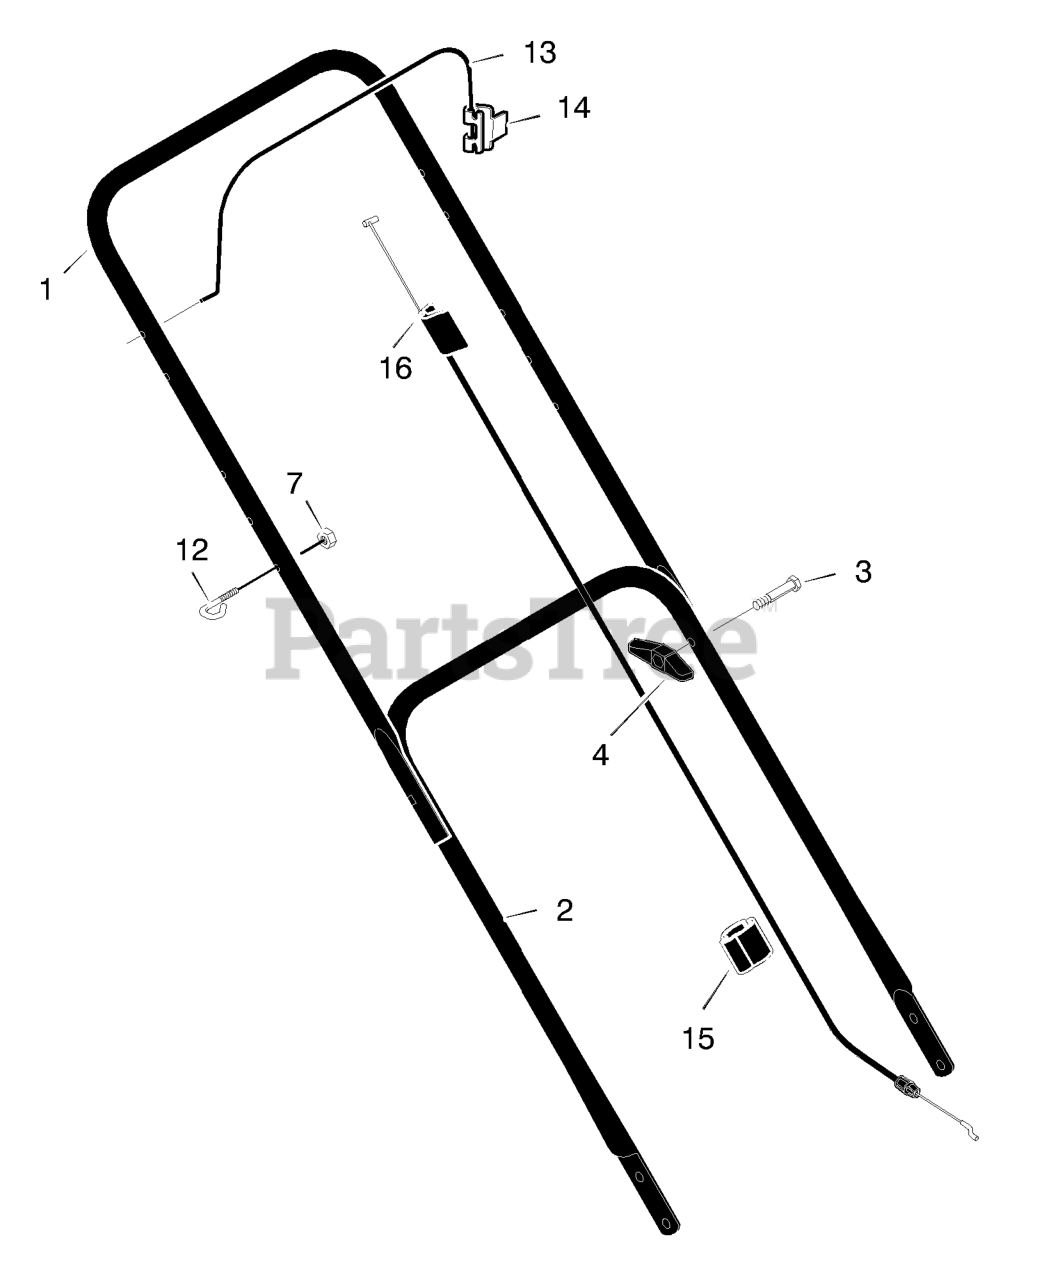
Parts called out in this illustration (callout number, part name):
1	Handle, Upper (Black)
2	Handle, Lower (Black)
4	Knob, Plastic
7	Locknut
12	Guide, Rope
13	Engine Stop Lever
14	Bracket, Stop Lever
15	Fastener, Cable
16	Engine Stop Cable
